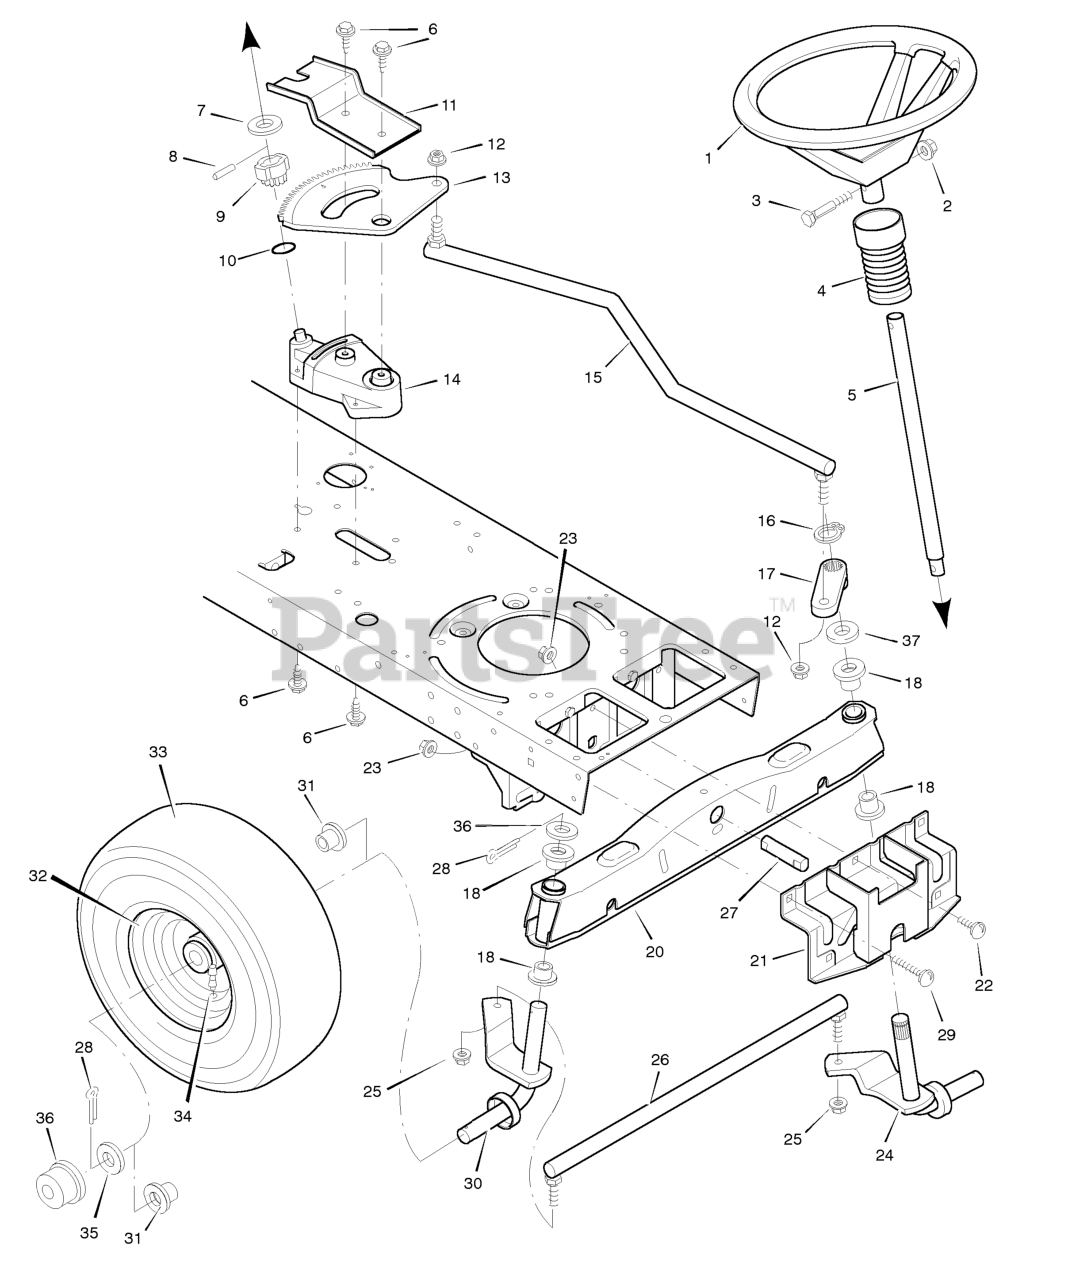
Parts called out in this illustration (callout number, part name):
1	Wheel, Steering
2	Nut, Hex
3	Bolt, Hex
4	Bellows
5	Post Assembly, Steering
7	Washer
8	Pin, Spring
9	Gear Assembly, Pinion
10	O-Ring
11	Clip, Gear Retainer
12	Locknut, Flange
13	Gear, Sector
14	Support, Steering
15	Link, Drag
17	Arm, Drag Link
18	Bearing
20	Axle Assembly (with grease fittings)
21	Hanger Assembly, Axle
22	Bolt, Carriage
23	Locknut, Flange
24	Spindle Assembly, Left
25	Locknut, Flange
26	Rod, Tie
27	Pin, Pivot
28	Pin, Cotter
29	Bolt, Carriage
30	Spindle Assembly, Right
31	Bearing, Wheel
32	Wheel & Tire Assembly
33	Tire *
34	Stem, Valve
36	Hub Cap
